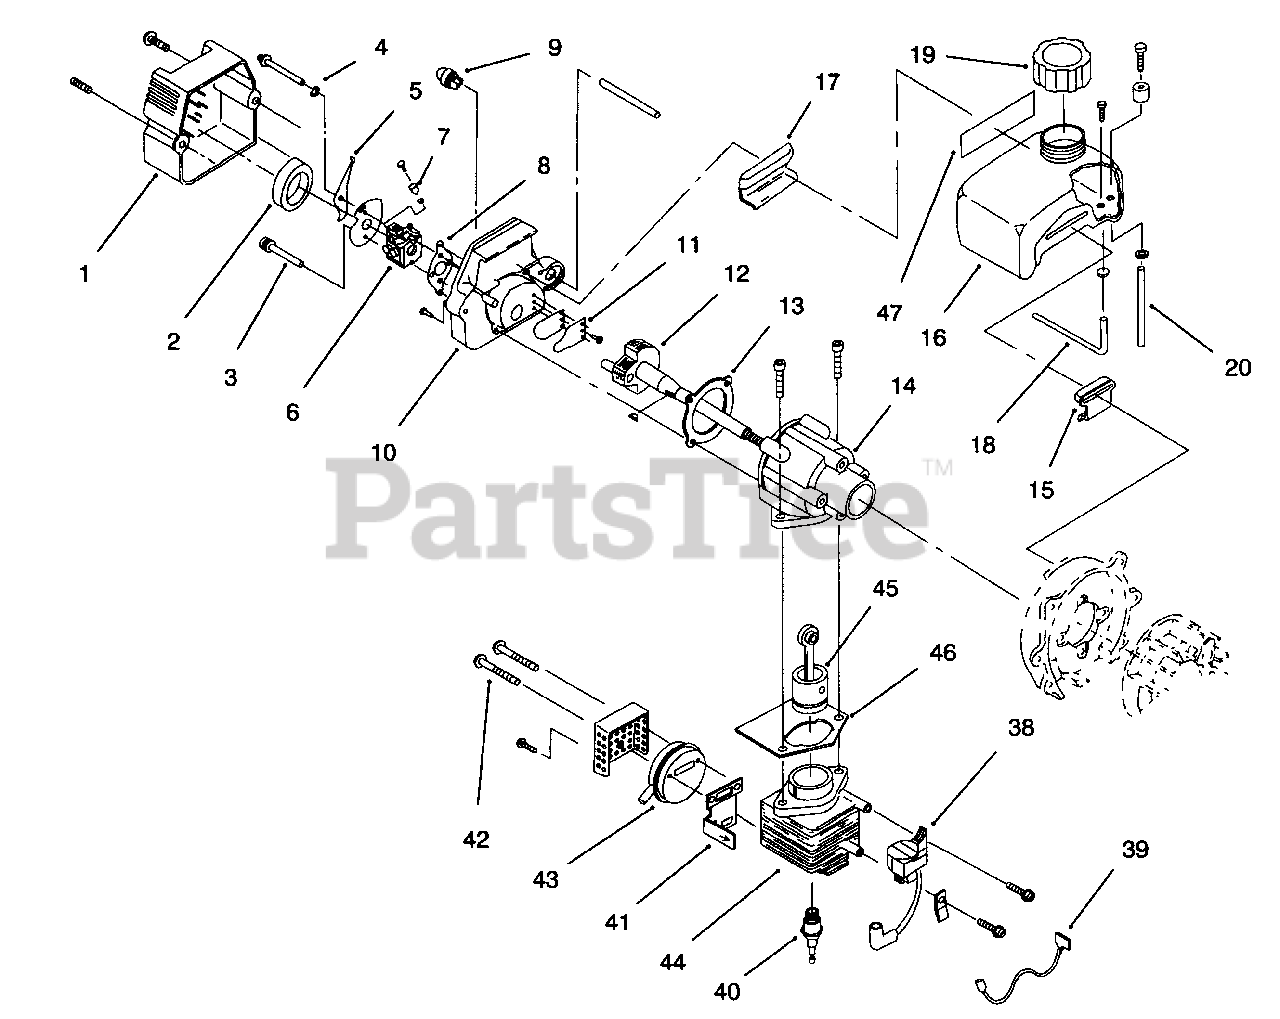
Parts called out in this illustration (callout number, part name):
1	Carburetor/Air Cleaner Asm. (Incl. Ref. #2)
2	Air Cleaner Filter
3	Carburetor Mounting Screw Asm.
4	Wavey Washer
5	Choke Lever and Plate
6	Carburetor Asm.
7	Throttle Adjustment Asm. (Walbro)
7	Throttle Adjustment Asm. (Zama)
8	Carburetor Gasket
9	Primer and Hose Asm.
10	Carburetor Mount Asm. (Incl. Ref. #11-13)
11	Reed Asm.
12	Power Shaft Asm.
13	Carburetor Mount Gasket
14	Crankcase Service Asm. (Incl. Ref. #12)
15	Front Mounting Pad
16	Fuel Tank Asm. (Incl. Ref. #21-23)
17	Rear Mounting Pad
18	Return Line Asm.
19	Fuel Cap Asm.
20	Fuel Line Asm.
38	Module Asm.
39	Wire Lead
40	Spark Plug
41	Exhaust Gasket
42	Muffler Mounting Bolt Asm.
43	Muffler Asm.
44	Cylinder Asm.
45	Piston and Rod Asm.
46	Cylinder Gasket
47	Decal-Fuel & Oil Mix
